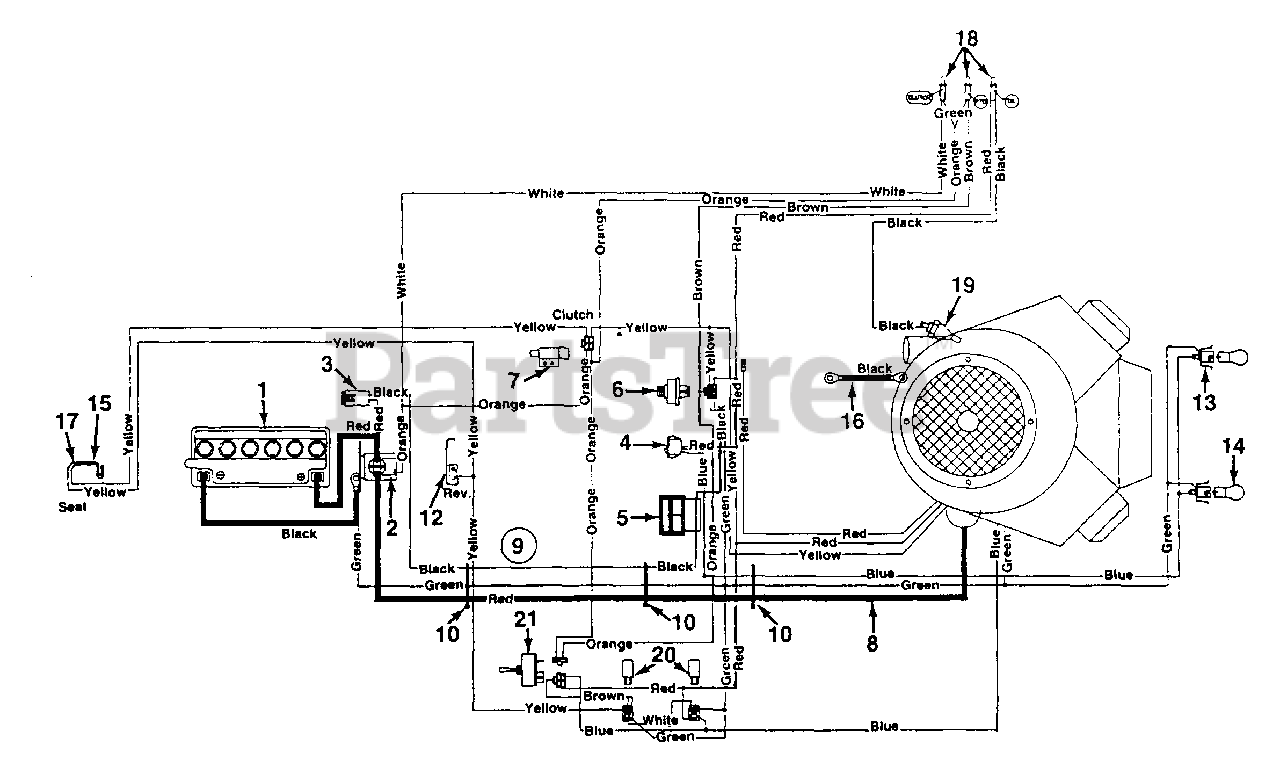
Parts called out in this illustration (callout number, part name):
1	Battery
2	Solenoid
3	Fuse 20 Amps
4	Light Switch
5	Ammeter
6	Ignition Switch
7	Safety Switch (Clutch)
8	Electric Wire 30" Lg.
9	Wire Harness
10	Cable Tie
12	Safety Switch (Reverse)
13	Socket
14	Bulb (Headlight)
15	Safety Switch (Seat)
16	Ground Wire 7.5" Lg.
17	Safety Switch (Seat)
18	Bulb
19	Oil Switch
20	Relay
21	PTO Switch
